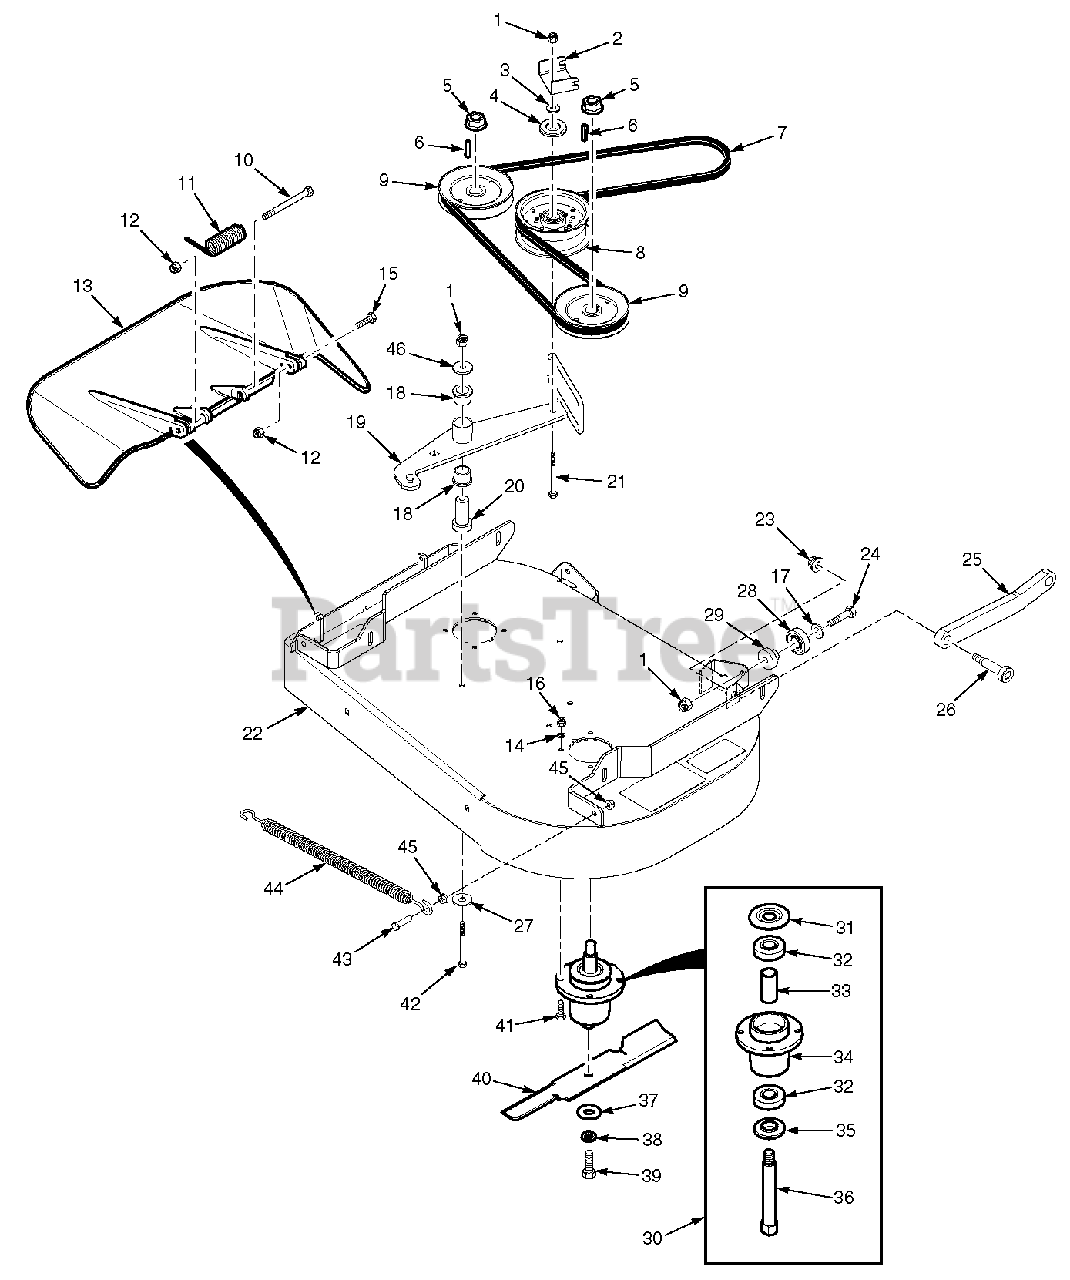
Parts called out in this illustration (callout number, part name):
1	Nut, Elastic Stop 3/8-16
2	Bracket, Belt Guide
3	Flatwasher, 3/8-.391 x .938 x .105
4	Dust Shield
5	Nut, 3/4-16 Spiral Lock
6	Key, 1/4 x 1/4 x 1-1/4"
7	Belt, Cutter Deck
8	Pulley, 5" Idler
9	Pulley, 5.73" OD - 25mm Bore
10	Bolt, Hex Head 5/16-18 x 4-3/4"
11	Spring, Discharge Chute
12	Nut, Elastic Stop 5/16-18
13	Discharge Chute Assembly
14	Lockwasher, 5/16 Spring
15	Bolt, Hex Head 5/16-18 x 1-3/4"
16	Nut, Elastic Stop 5/16-18
17	Flatwasher, 3/8-.391 x .938 x .105 Hardened
18	Bearing, Plastic
19	Idler Arm
20	Pivot, Idler
21	Bolt, Hex Head 3/8-16 x 3-1/4"
22	Cutter Deck w/Decals, SMWZT-36
23	Nut, Elastic Flange 3/8-16
24	Bolt, Hex Head 3/8-16 x 1-3/4"
25	Pusharm
26	Bolt, Shoulder 1/2 x 3/8-16 x 2-3/4"
27	Flatwasher, 3/8-.406 x 2.25" x .188
28	Bearing
29	Spacer, Bearing
30	Spindle Assembly
31	Debris Shield
32	Bearing
33	Spacer, Bearing
34	Spindle Housing Assembly
35	Protector, Bearing
36	Shaft, Spindle
37	Flatwasher, 5/8-11 x 1-1/2"
38	Lockwasher, 1/2 Spring
39	Bolt, Hex Head 5/8-11 x 1-1/2"
40	Cutter Blade, 18"
41	Bolt, Hex Head 5/16-18 x 1-1/2"
42	Bolt, Hex Head 3/8-16 x 3-3/4"
43	Bolt, Hex Head 3/8-16 x 1-1/2"
44	Spring, Idler
45	Nut, Serrated Flange 3/8-16
46	Flatwasher, 3/8-.406 x 1-1/2"
